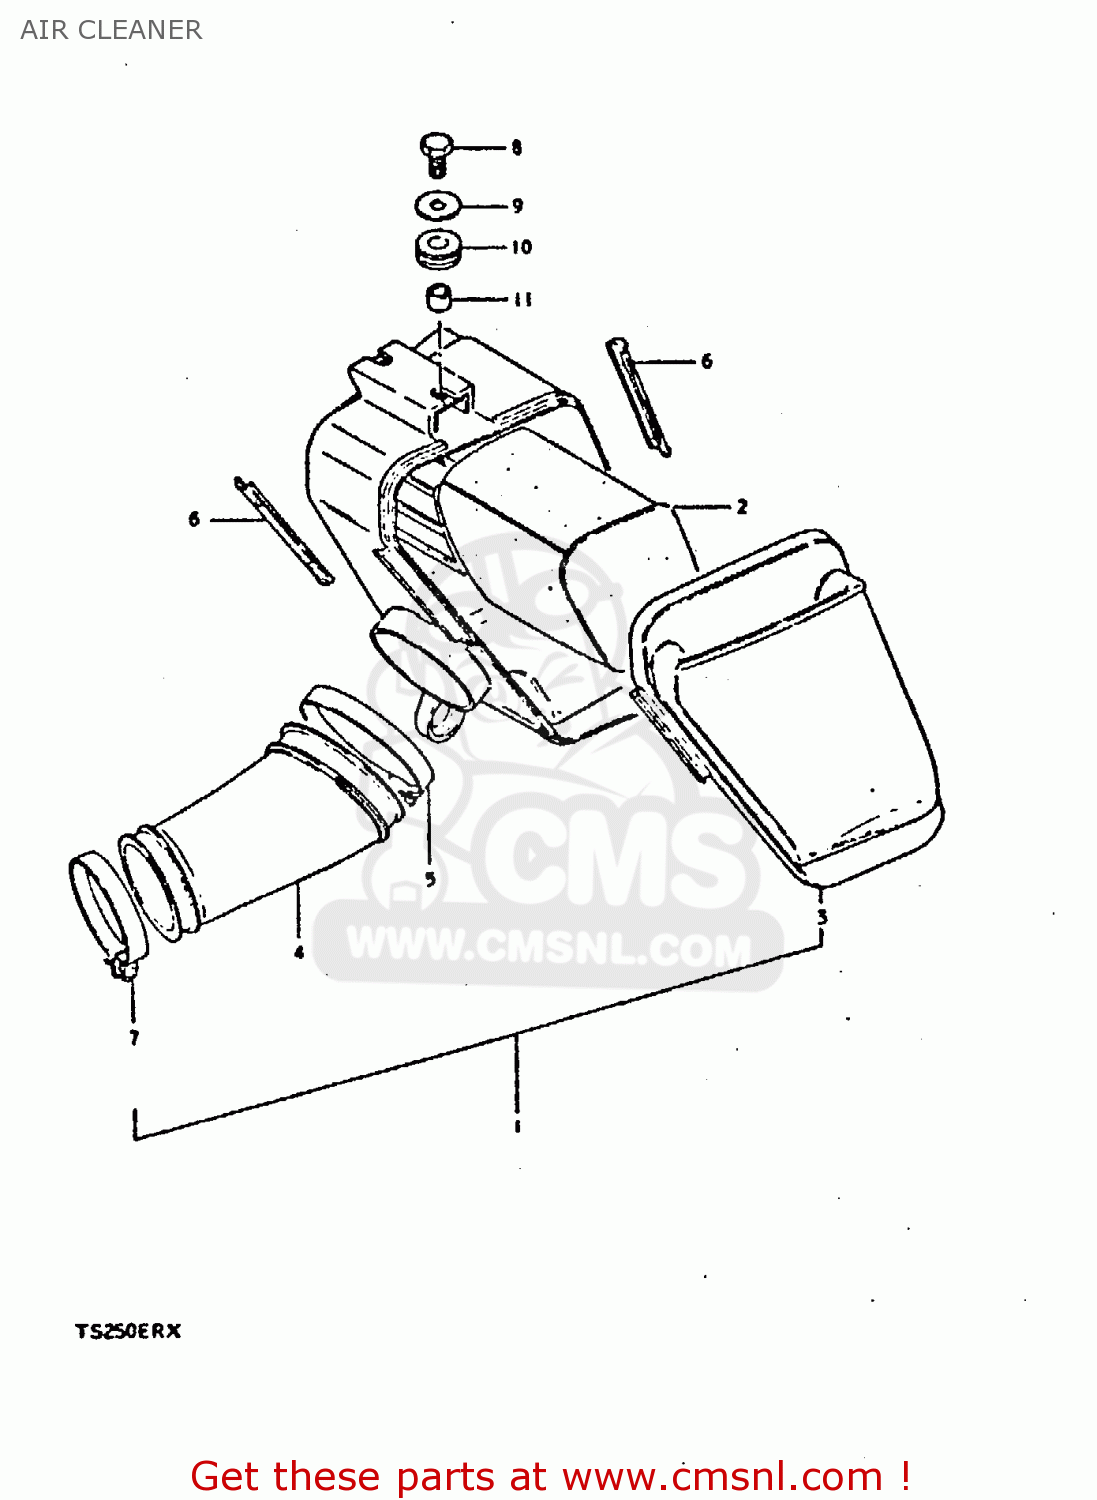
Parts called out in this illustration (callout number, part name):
1	CLEANER ASSEMBLY,AIR
2	FILTER
3	CAP,AIR CLEANER
4	OUTLET
5	CLAMP
6	SLIDER
7	CLAMP
8	BOLT, UPPER
9	WASHER (6.5X20X1.2)
10	CUSHION
11	SPACER (7X9X7)
